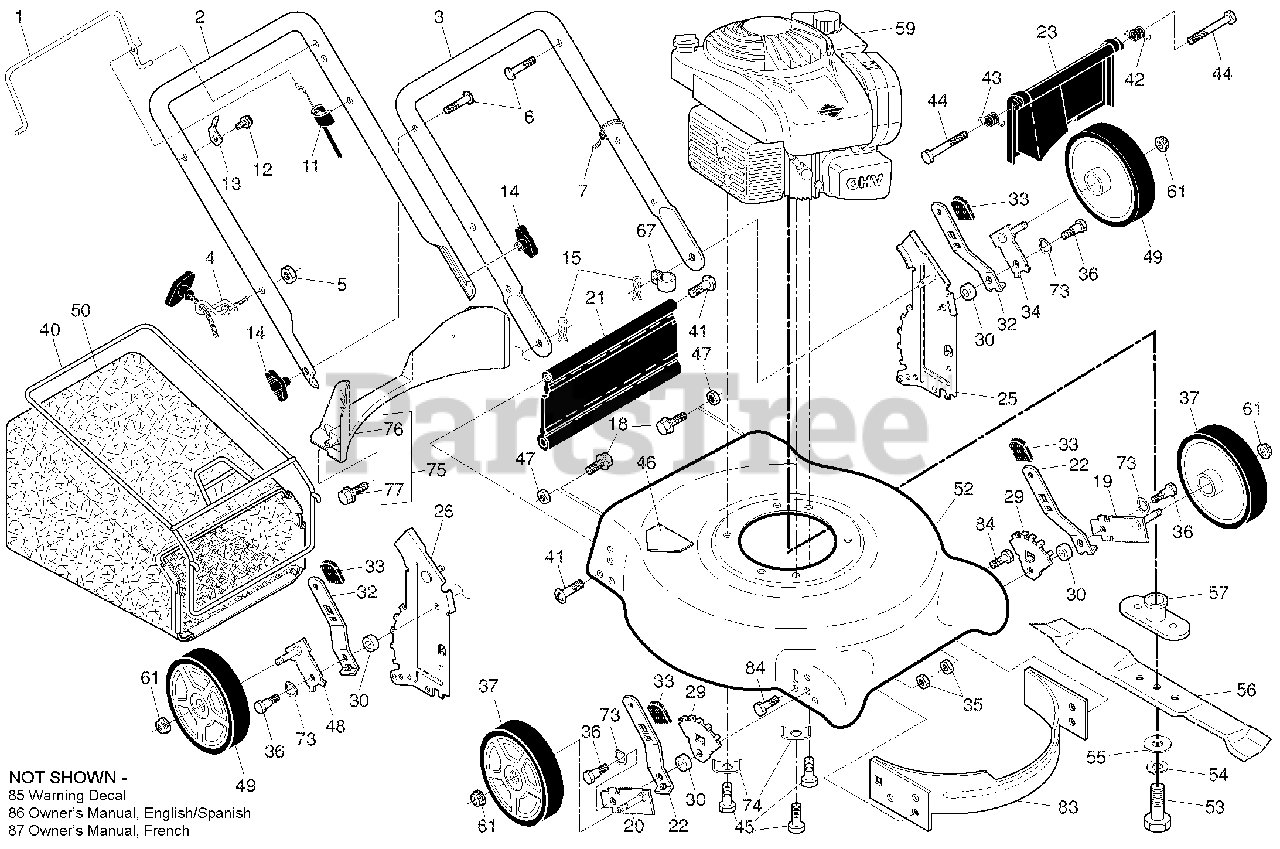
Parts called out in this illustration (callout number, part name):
1	CONTROL BAR
2	UPPER HANDLE
3	COVER MANDREL RH
4	Rope Guide
5	Nut, Hex
6	Handle Bolt
7	Wire Tie
11	ENGINE ZONE CONTROL CABLE
12	SCREW, HEX WASHER HEAD
13	UP-STOP BRACKET
14	Handle Knob
15	Hairpin Cotter
18	SCREW.HEX.WASHEAD.1/4-20 X 3/8
19	Axle Arm Assembly, Front, LH
20	Axle Arm Assembly, Front, RH
21	Kit, Rear Skirt
22	Selector Spring, Front
23	Rear Door Assembly
24	Locknut, Hex 5/16-18
25	HANDLE BRACKET ASSEMBLY, LH
26	HANDLE BRACKET ASSEMBLY, RH
29	WHEEL ADJUSTING BRACKET, FRONT
32	SELECTOR SPRING, REAR
33	Selector Knob
34	AXLE ARM ASSEMBLY, REAR
36	Shoulder Bolt
37	WHEEL & TIRE ASSEMBLY
40	Frame, Grassbag
41	Hinge Screw
42	Spring, Rear Door, LH
43	Spring, Rear Door, RH
44	Bolt, Rear Door
45	Screw, Hex Head, Threaded, Rol
46	Danger Decal
47	NUT.CENTER LOCK.5/16-18 UNC
49	WHEEL & TIRE ASSEMBLY
50	Grassbag
52	KIT, LAWN MOWER HOUSING
53	Screw, Hex Head, Grade 8 3/8-2
54	Helical Lockwasher
55	Hardened Washer
56	21" Blade
57	BLADE ADAPTER
58	Hinge Spring
59	Engine, Briggs & Stratton, Model Number 9P702-0025-F1 (For engine service and replacement parts,
61	Nut, Hex
67	Clip, Cable
73	Washer, Curved, Cylindrical
74	Washer, Special, Engine
75	Kit, Rear Baffle (Includes 3 S
76	Baffle, Rear
77	Screw, Rear Baffle
83	BAFFLE, FRONT
84	BOLT.5/16-18HEX.WHS.HD.LCKSERR
86	OWNER'S MANUAL ENGLISH / SPAN
87	OWNER'S MANUAL, FRENCH
